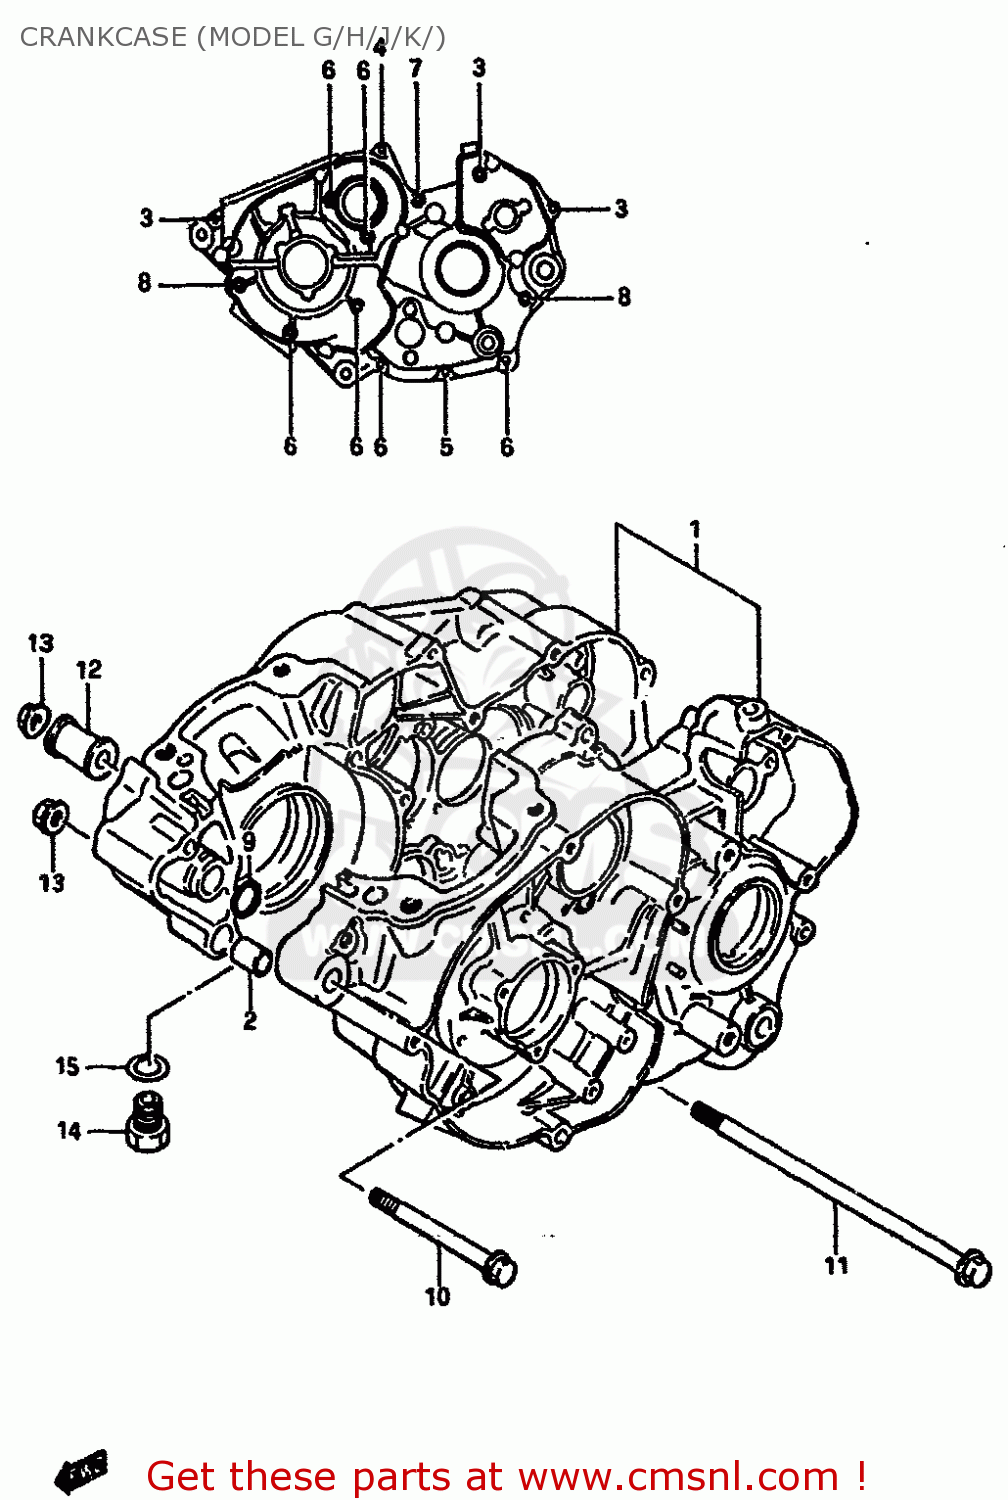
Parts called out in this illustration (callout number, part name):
1	CRANKCASE SET
2	PIN(8X13X22)
3	SCREW
4	SCREW
5	SCREW
6	SCREW
7	SCREW (6*60)
8	SCREW
9	O RING(D:1.9,ID:13.8)
10	BOLT(8X100)
11	BOLT(8X215)
12	SPACER,ENGINE MOUNTING (L:32)
13	NUT
14	PLUG
15	GASKET(14X19.2X2) (NAS)
